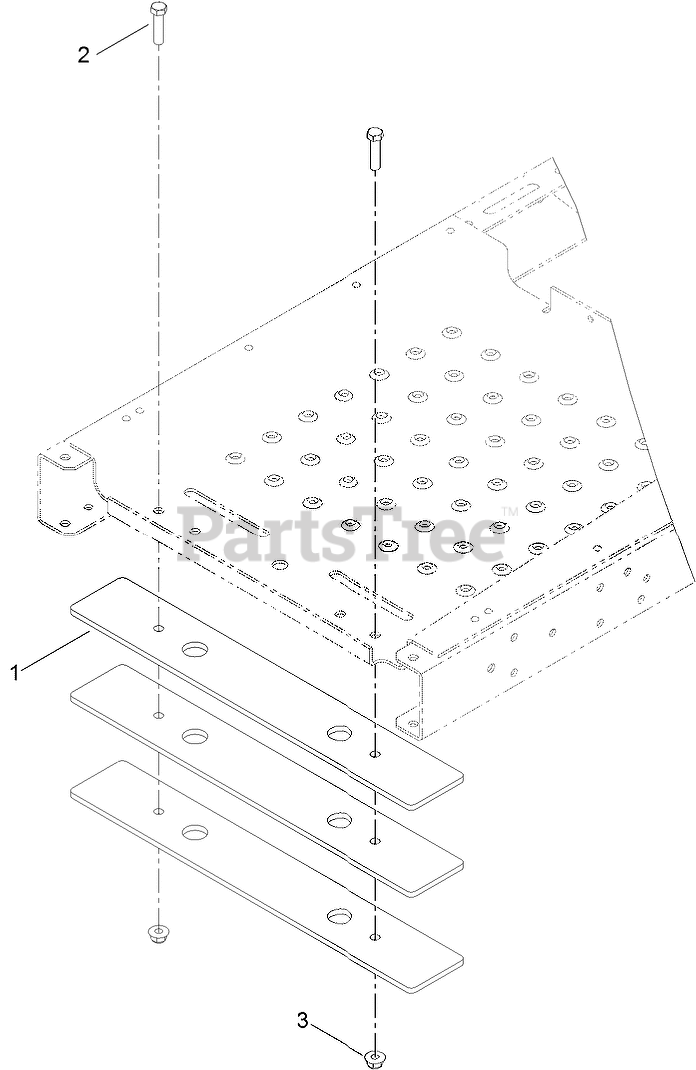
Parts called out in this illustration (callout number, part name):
1	PLATE-WEIGHT
2	SCREW-HH
3	NUT-HF, NI
